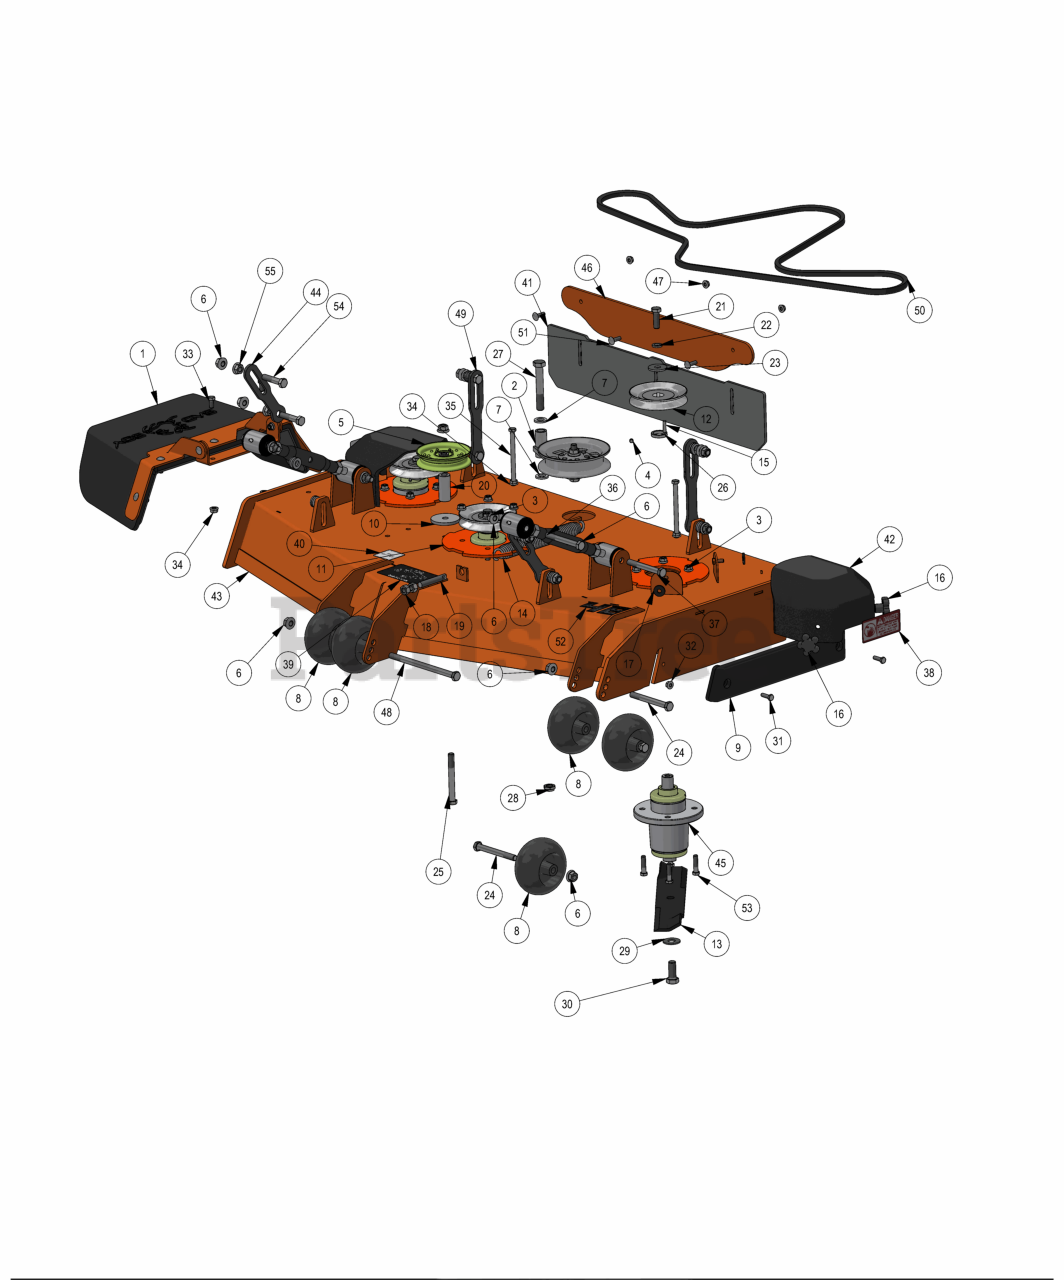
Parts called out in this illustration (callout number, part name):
1	2019 Outlaw Gen2 Chute Assembly
2	2019 Revolt Deck Idler Assembly
3	3/8-16 NYLON INSERT FLANGE LOCKNUT (GR.F) ZINC
4	5/16-24 X 1/4 SOCKET SET SCREW (CUP PT) PLAIN
5	4 3/4 Idler Pulley - ABFI-76
6	1/2-13 NYLON INSERT FLANGE LOCKNUT ZINC
7	.635 ID X 1.120 OD X .140 THICK FLAT WASHER NYLON
8	2019 Deck Wheel
9	REVISED TRIM BUMPER_20180226
10	MZ Deck Idler Spacer
11	Deck Spindle Support Plate
12	5" Spindle Deck Pulley
13	48" ZT/Mav/Compact Outlaw Blade with Fusion
14	2019 Outlaw Gen2 Deck Spring
15	1/4 X 1 SQ MACHINERY KEY 1018 STL PLN
16	5/16" Knob
17	.360 ID X .983 OD X .120 THICK FLAT WASHER NYLON BLACK
18	1/2-13 HEX NUT ZINC
19	All Thread
20	2019 Revolt Stationary Idle Spacer
21	1/2-20 X 1-1/2 HEX CAP SCREW (GR.5) ZINC
22	1/2 SPLIT LOCKWASHER (GR.8) ZINC/YELLOW
23	1/2 BELLEVILLE WASHER (1-5/8 OD X .140 THK) ZINC
24	1/2-13 X 4-1/2 HEX CAP SCREW (GR.5) ZINC
25	1/2-13 X 4-1/4 HEX CAP SCREW (GR.5) ZINC
26	1.02 ID X 1.38 OD X .250 THK SPACER ZINC
27	5/8-11 X 4 HEX CAP SCREW (GR.8) ZINC YELLOW
28	5/8-11 NYLON INSERT JAM LOCKNUT ZINC
29	5/8 USS FLAT WASHER (1-3/4" OD) GR.8 ZINC YELLOW
30	5/8-18 X 1-1/2 HEX CAP SCREW (GR.8) ZINC YELLOW
31	5/16-18 X 1 HEX CAP SCREW (GR.5) ZINC
32	5/16-18 NYLON INSERT FLANGE LOCKNUT ZINC
33	3/8-16 X 3/4 HEX CAP SCREW (GR.5) ZINC
34	3/8-16 HEX SERRATED FLANGE NUT HARD/ZINC
35	3/8-16 X 5-1/2 HEX CAP SCREW (GR.5) ZINC
36	Turnbuckle
37	1/2-13 X 4 HEX CAP SCREW (GR.8) ZINC YELLOW
38	Danger Decal-Spindle/Discharge
39	2019 Revolt Deck Belt Route Decal
40	Deck Impact Patent Decal 9591803
41	2023 MZ Stripping Kit Rubber
42	2023 Revolt pulley cover
43	2023 Revolt 48'' DECK
44	Deck Hanger
45	OUTLAW SPINDLE ASSEMBLY
46	Striping Kit Plate
47	5/16-18 HEX SERRATED FLANGE NUT HARD/ZINC
48	1/2-13 X 8 HEX CAP SCREW GR 5 ZINC
49	2023 Stand-On Rear Deck HangerV2
51	5/16-18 X 1 CARRIAGE BOLT (GR.8) ZINC
52	48" Deck Decal
53	3/8-16 X 1-1/2 HEX CAP SCREW (GR.5) ZINC
54	1/2-13 X 2-1/4 HEX CAP SCREW (GR.5) ZINC
55	1/2-13 HEX SERRATED FLANGE NUT HARD/ZINC
56	.505 ID X 1.000 OD X .125 THICK FLAT WASHER NYLON
